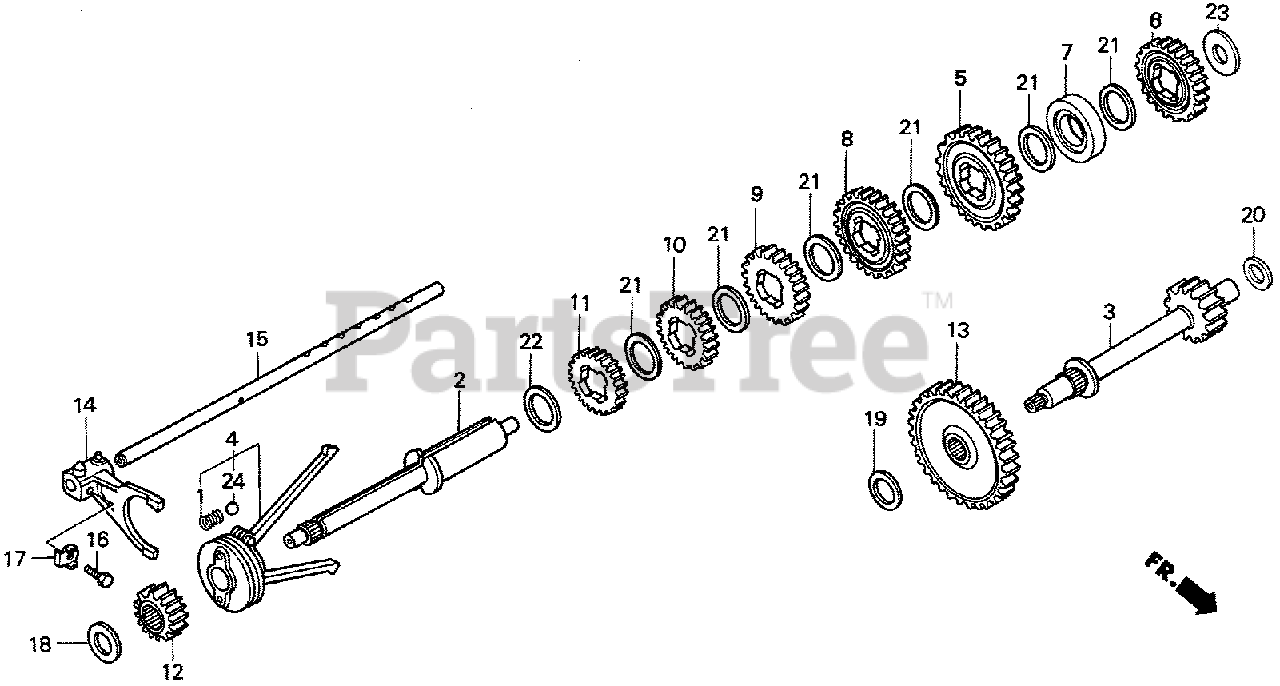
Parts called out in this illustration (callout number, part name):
1	SPRING, CHANGE KEY
2	SHAFT, CHANGE
3	COUNTERSHAFT
4	HOLDER, KEY (NOT AVAILABLE)
5	GEAR, CHANGE LOW (48T)
6	GEAR, REVERSE CHANGE (41T)
7	POSITIONER, NEUTRAL
8	GEAR, CHANGE SECOND (43T)
9	GEAR, CHANGE THIRD (37T)
10	GEAR, CHANGE FOURTH (34T)
11	GEAR, CHANGE FIFTH (32T)
12	GEAR, COUNTERSHAFT DRIVE (16T)
13	GEAR, COUNTERSHAFT DRIVEN (49T)
14	FORK, SHIFT
15	SHAFT, SHIFT FORK
16	BOLT, SHAFT FORK SETTING
17	WASHER, LOCK (6MM)
18	WASHER, THRUST (15MM) (NOT AVAILABLE)
19	WASHER, THRUST (20MM)
20	WASHER, THRUST (18MM)
21	WASHER, DISTANCE (2MM)
22	WASHER, DISTANCE (1MM)
23	WASHER, CHANGE THRUST (NOT AVAILABLE)
24	BALL, STEEL (#10) (5/16)
